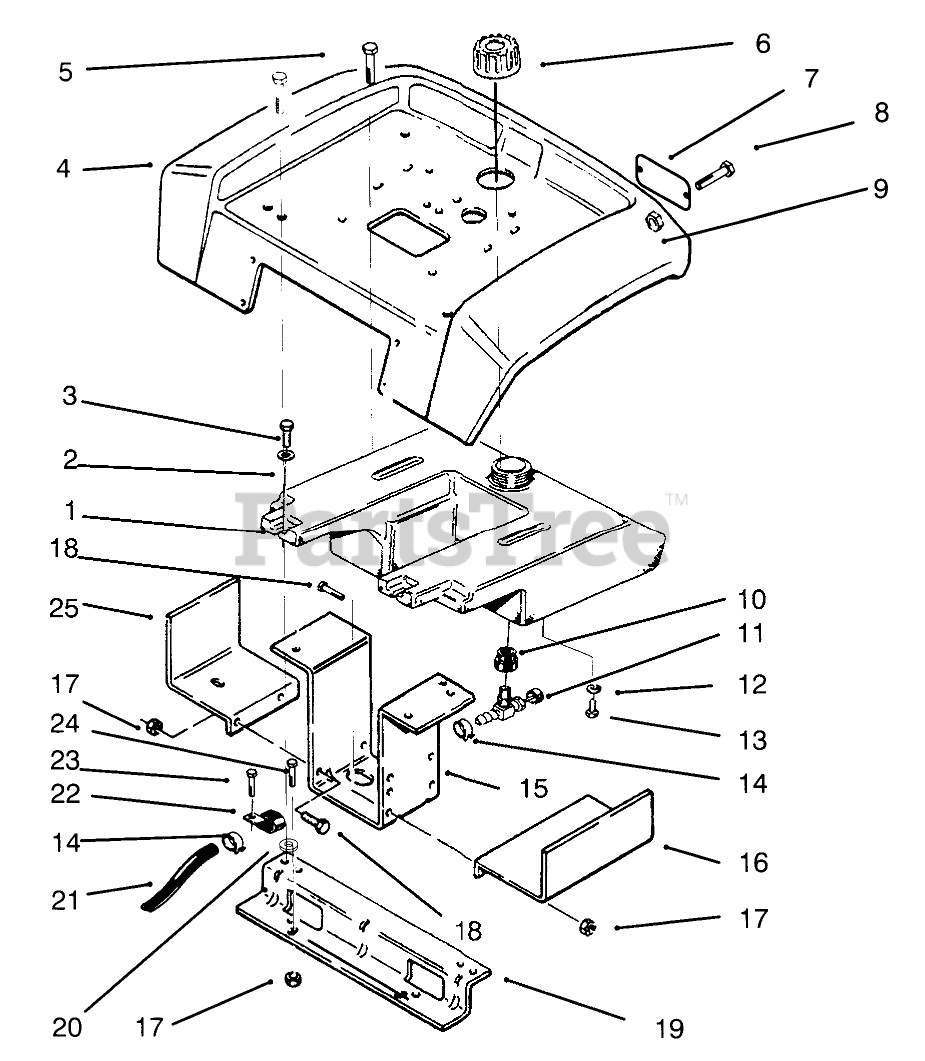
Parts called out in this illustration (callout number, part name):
1	TANK-FUEL
2	WASHER-FLAT
4	Fender
5	SCREW
6	GAS CAP ASM
7	Reflector
8	SCREW-PPH
9	NUT-LOCK, NI
10	BUSHING
11	VALVE-FUEL
12	WASHER-LOCK
13	SCREW-HH
14	CLAMP-HOSE
15	Fuel Tank Support LH
16	Bracket-Fender
17	NUT-LOCK, NI
18	SCREW-HH
19	BRACKET-FENDER B
20	WASHER-PLAIN
21	Line-Fuel 62"
22	CLIP
23	SCREW-HH, LOCK
24	SCREW-HH
25	Support-FueITank RH
